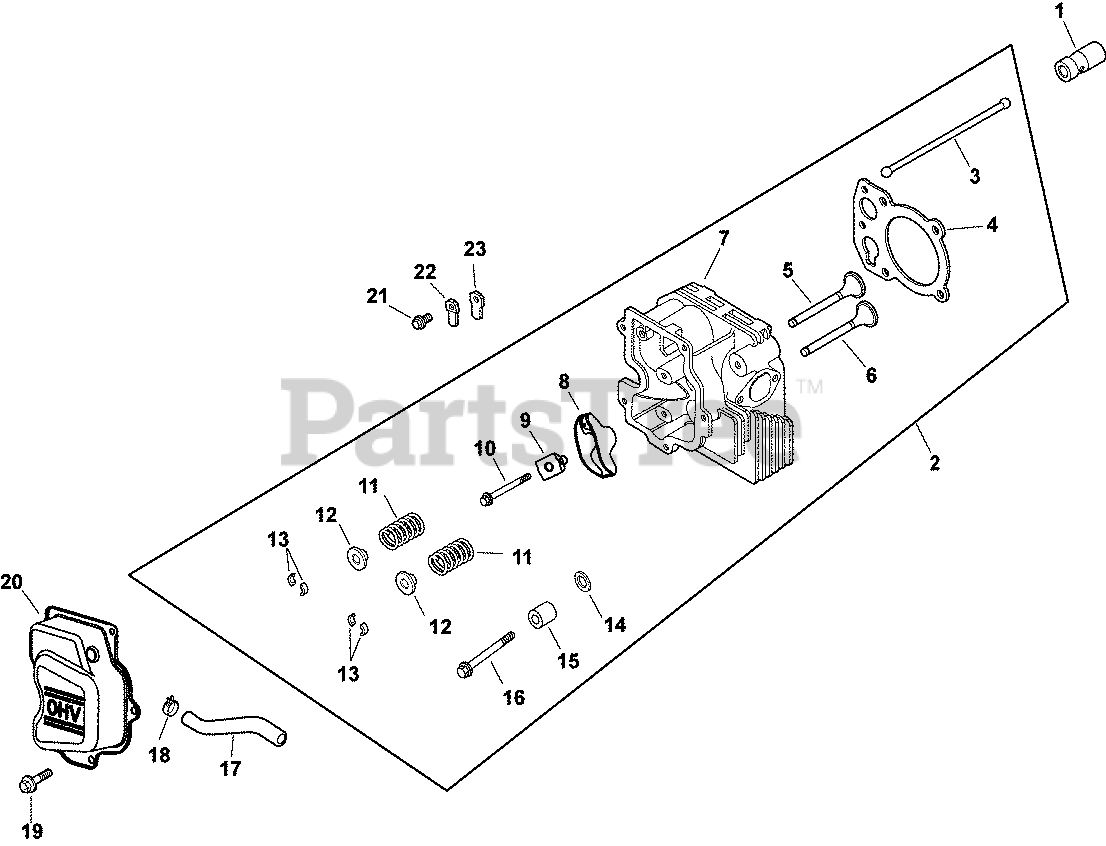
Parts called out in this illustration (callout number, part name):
1	LIFTER, HYDRAULIC VALVE-USE 25 351 10-S
2	KIT, CYLINDER HEAD
3	ROD, PUSH
4	GASKET, CYLINDER HEAD
5	VALVE, EXHAUST
6	VALVE, INTAKE
7	KIT, HEAD, CYLINDER
8	ARM, ROCKER
9	PIVOT, ROCKER ARM
10	SCREW, FLG M6X1.0X34
11	SPRING, VALVE
12	RETAINER, VALVE SPRING - USE 25 173 28-S
13	KIT, RETAINER
14	WASHER, FLAT 13/32"
15	SPACER, HEAD BOLT EXHAUST PORT
16	SCREW, CYLINDER HEAD (M10 X 80)
17	HOSE
18	CLAMP, HOSE (KM)-USE 25 237 31-S
19	SCREW,FLG THD FRM M6X1.0X16-(#25086397S)
20	COVER, ROCKER
21	SCREW, FLG THD FRM M5X.8X10
22	RETAINER, REED
23	REED, BREATHER
1232630-S	HOSE, BREATHER
